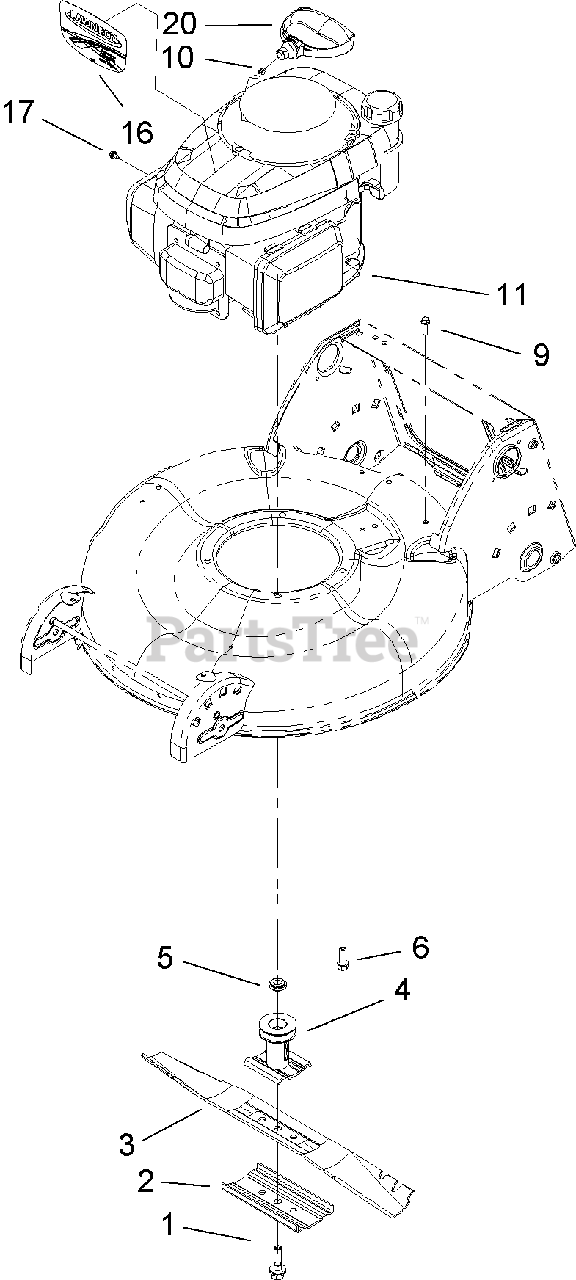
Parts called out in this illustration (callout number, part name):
1	BOLT-BLADE
2	SUPPORT-BLADE
3	BLADE-21 INCH
4	BLADE DRIVER ASM
5	Spacer-Driver
6	SCREW
9	SCREW-HWH
10	STOP-ROPE
17	SCREW-HWH
20	HANDLE-RECOIL
